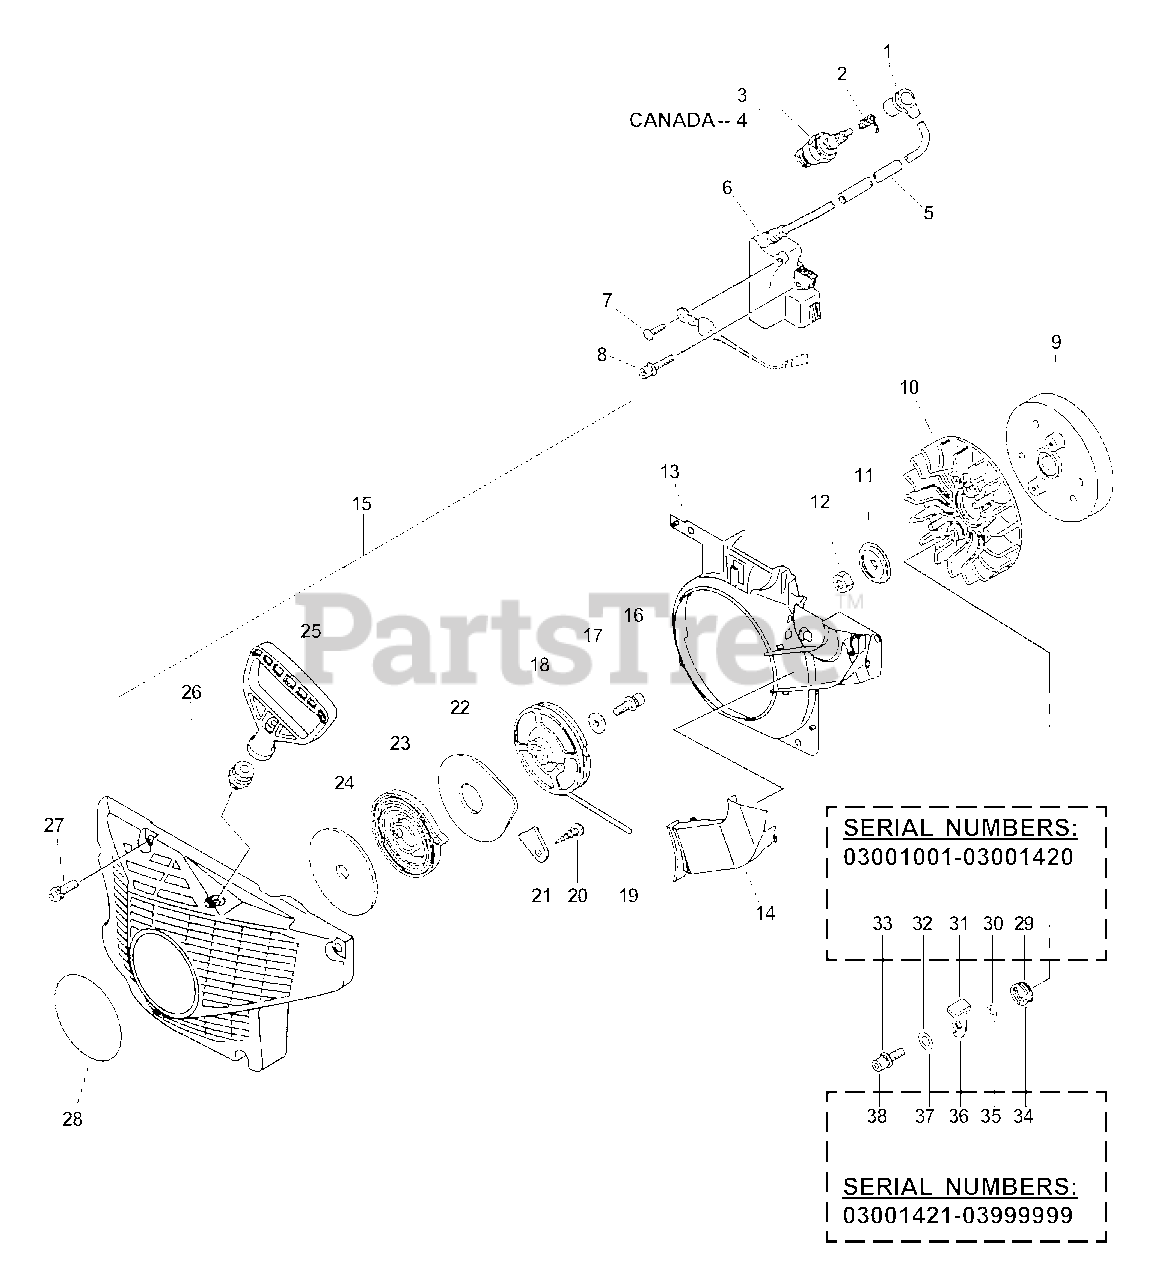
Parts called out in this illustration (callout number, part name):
1	CAP, SPARK PLUG
2	TERMINAL, SPARK PLUG
3	SPARK PLUG - BPM7A
4	SPARK PLUG - BPMR7A
5	TUBE
6	COIL, IGNITION
7	SCREW 4×8
8	BOLT 4×20
9	FLYWHEEL
11	WASHER 8.2×31×0.8
13	COVER, FAN
14	DUCT, AIR
15	STARTER ASSY
16	BOLT 5×14
17	WASHER 5.5×12×0.8
18	REEL, ROPE
19	ROPE, STARTER 4.0×950
20	SCREW 4×8
21	PLATE, EYE
22	PLATE, STARTER
23	SPRING, RECOIL
24	PLATE, STARTER
25	GRIP, STARTER
26	GUIDE, ROPE
27	BOLT 5×20
28	LABEL, ECHO
29	SPRING, RETURN
30	SPACER
31	PAWL, STARTER
32	WASHER 5.5×12×0.8
33	BOLT 5×14
34	SPRING, RETURN
35	COLLAR 5
36	PAWL, STARTER
37	WASHER 5.5×12×0.8
38	BOLT 5×20
